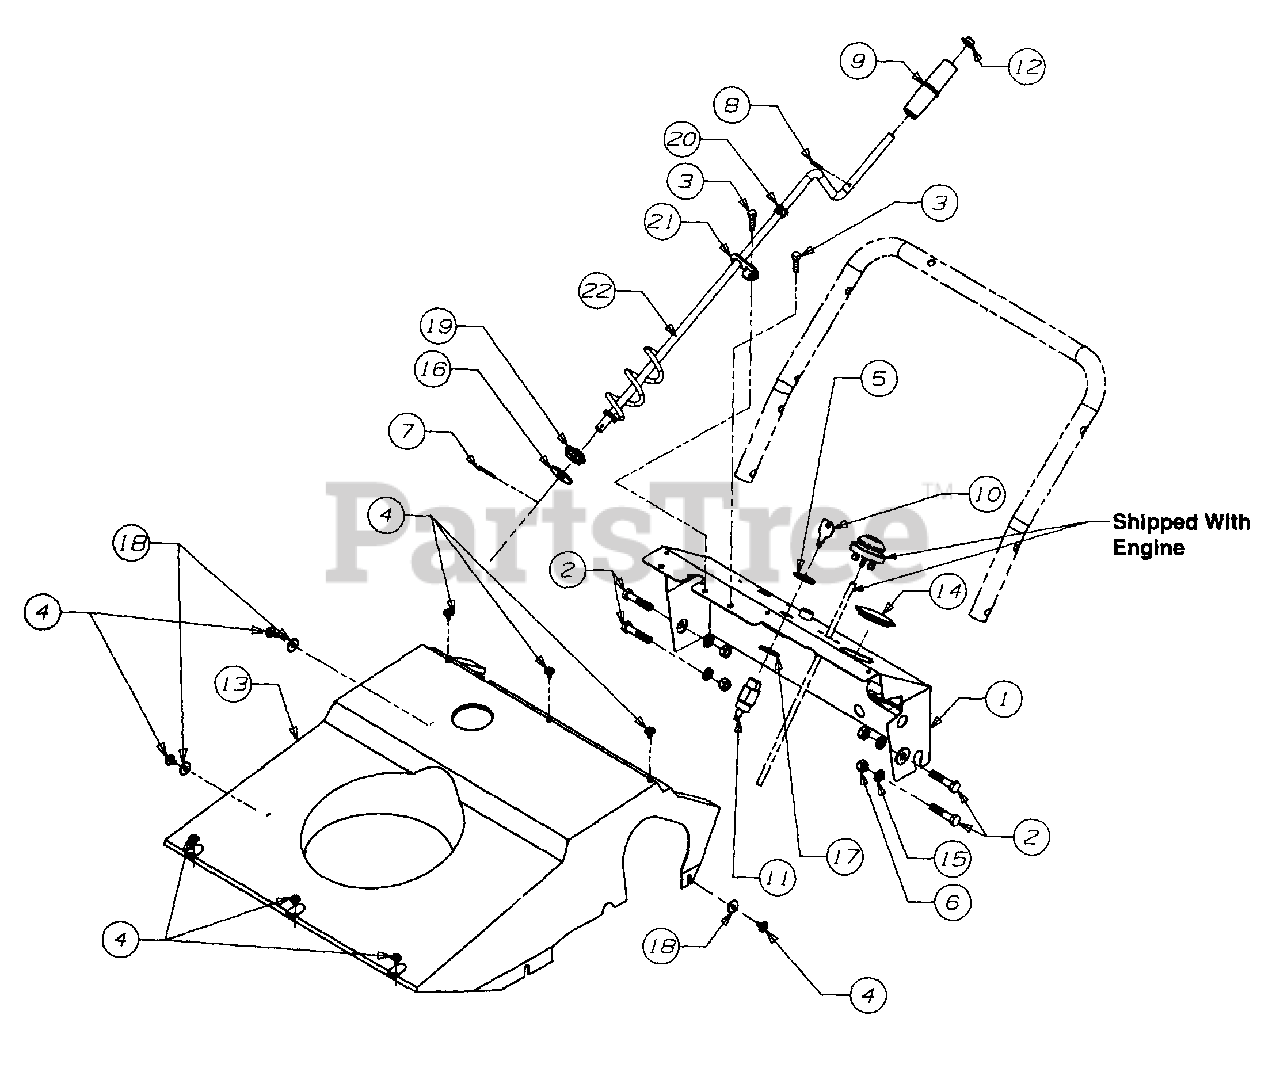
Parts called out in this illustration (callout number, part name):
3	Screw - Hex Tap
4	Screw - Hex Tap
5	Nut Hex
6	Nut - Hex
7	Pin - Cotter
8	Pin Roll
9	Knob - Chute Crank
10	Key - Ignition
11	Switch - Key
12	Nut Push
13	Shroud
15	Washer Lock
16	Washer Flat
17	Washer Internal Lock
18	Washer Flat
19	Bushing Hex
20	Bushing
21	Bracket Chute Crank
22	Crank Ass'y. Chute
